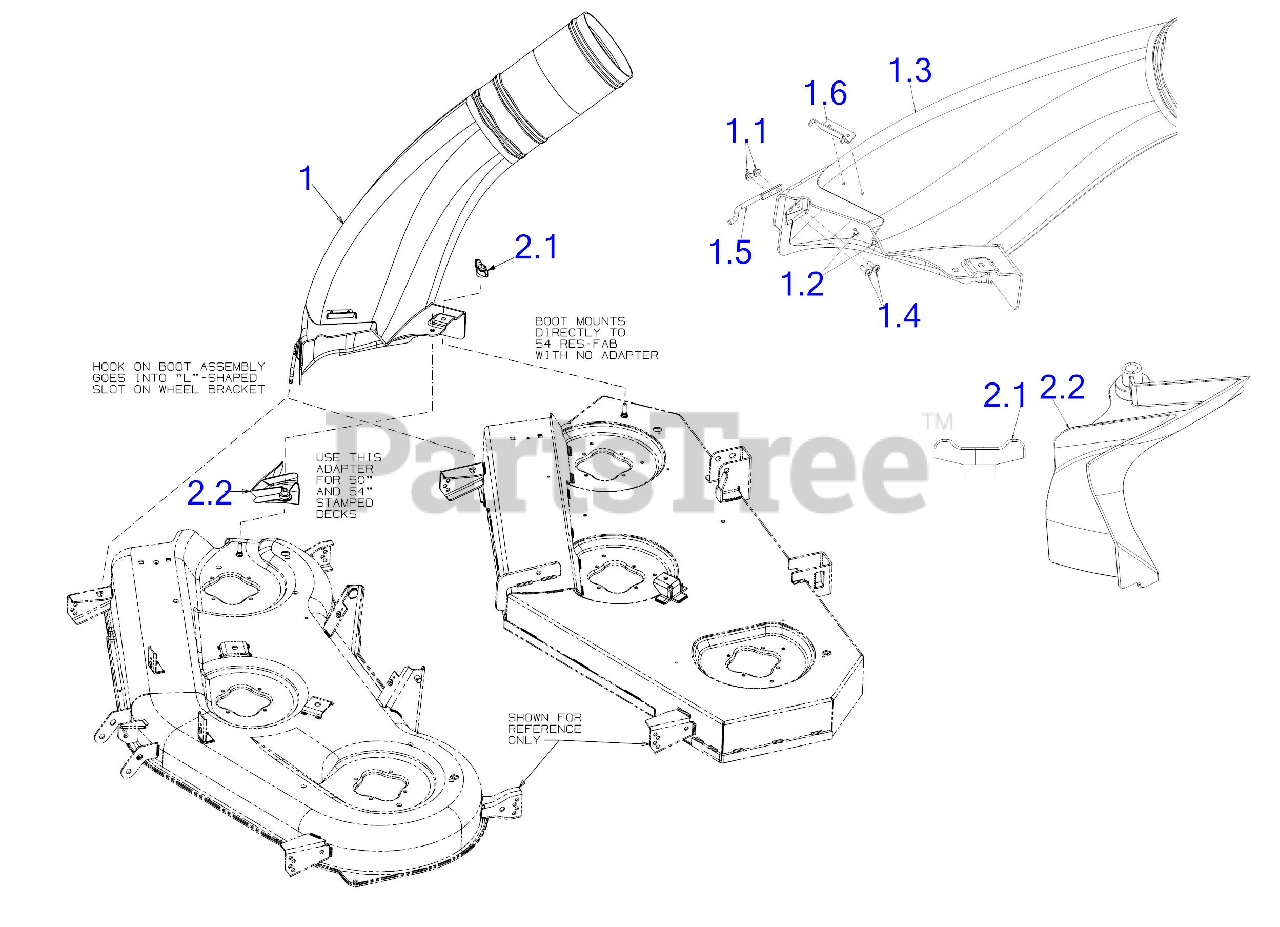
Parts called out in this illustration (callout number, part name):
1	LOWER CHUTE ASSEMBLY
1.1	FLANGE LOCK NUT
1.2	POP RIVET
1.3	DISCHARGE CHUTE
1.4	SCR-SHLDR 1/4-20 x .75 TORX
1.5	LOWER CHUTE MOUNTING ROD
2.1	WING KNOB 5/16-18
2.2	CHUTE ADAPTER
